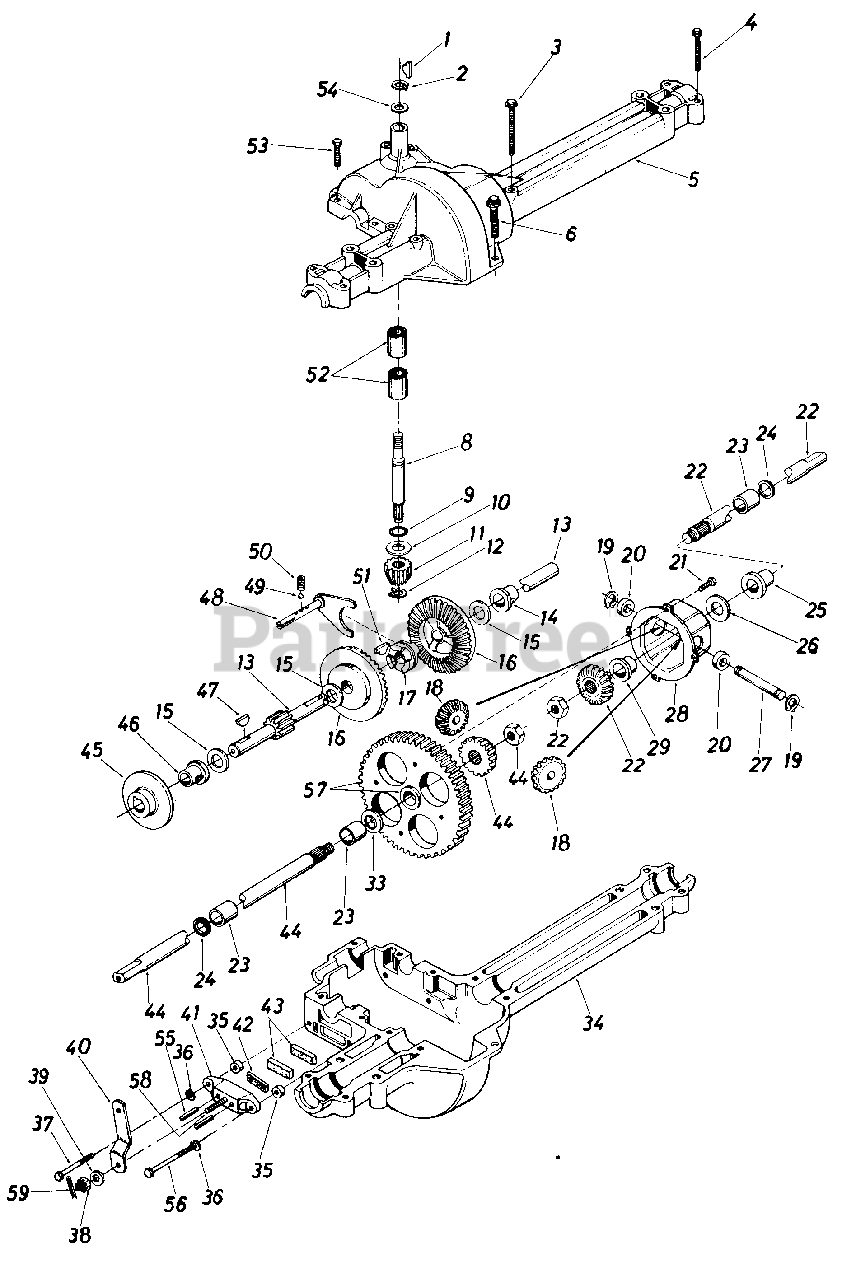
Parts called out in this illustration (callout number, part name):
1	#4 Hi-Pro Key 3/32 x 5/8" Dia.
2	Snap Ring .625" Shaft
3	Hex Bolt 1/4-20 x 1.75" Lg.
4	Hex Tap Scr. 1/4-20 x 1.25" Lg.
5	Upper Housing
6	Hex TT-Tap Scr. 1/4-20 x .75" Lg.
8	Input Shaft
9	Square Seal 5/8" I.D.
10	Thrust Washer 5/8" I.D. x 1.25 O.D.
11	Pinion Input 14T
12	Retaining Ring 7/16" Ext.
13	Drive Shaft
14	Flange Brg. 518" I.D. x 3/4" Lg.
15	Fl-Wash. (See Below)
15	Fl-Wash. 5/8" I.
16	Bevel Gear 42T
17	Clutch Collar
18	Miter Gear 15T (H.D.)
19	Retainer Ring
20	Thrust Bearing
21	Pan Head Scr. 1/4-20 x .50" Lg. w/Patch
22	Axle R.H. Ass'y.-Kit
23	Sleeve Bearing 3/4" I.D. x 1.0" Lg.
24	Oil Seal 3/4" I.D.
25	Flange Bearing 3/4" I.D. x 15/16" Lg.
26	Fl-Wash. .760" I.D. x 1.5" O.D.
27	Cross Shaft
28	Differential Housing Ass'y.
33	Fl-Wash. .760" I.D. x 1.5" O.D.
34	Lower Housing
35	Spacer .53" O.D. x 3/8" Lg.t
36	L-Wash. 1/4" I.D.t
37	Hex Bolt 1/4-20 x 1.50" Lg. (Grade 5)t
38	Castle Nut 5/16-24 Thd.t
39	Fl-Wash. .344" I.D. x 375n O.D.t
40	Actuating Armt
41	Brake Yoket
42	Puck Platet
43	Brake Puckt
44	Axle L.H. Ass'y.-Kit
45	Brake Disct
46	Flange Bearing 5/8" I.D. x 15/16" Lg.
47	Woodruff Key 3/16 x 5/8 HT
48	Shift Fork Ass'y.
49	Ball Detent .250" Dia.
50	Spring Detent
51	#9 Hi-Pro Key 3/16" x 3/4n Dia. HT
52	Needle Brg. 5/8" I.D. x 1/2" Lg.
53	Hex Bolt 1/4-20 x 1.00" Lg.
54	Fl-Wash. 5/8" I.D. x .030
55	Actuating Pin 5/16" Dia.t
56	Hex Bolt 1/4-20 x 2.50" Lg. (Grade 5)t
57	Differential Gear 72T Ass'y. w/Bearing
58	Sq. Hd. Bolt 5/16-24 Thd.t
59	Cotter Pin 3/32" Dia. x 1" Lgt
